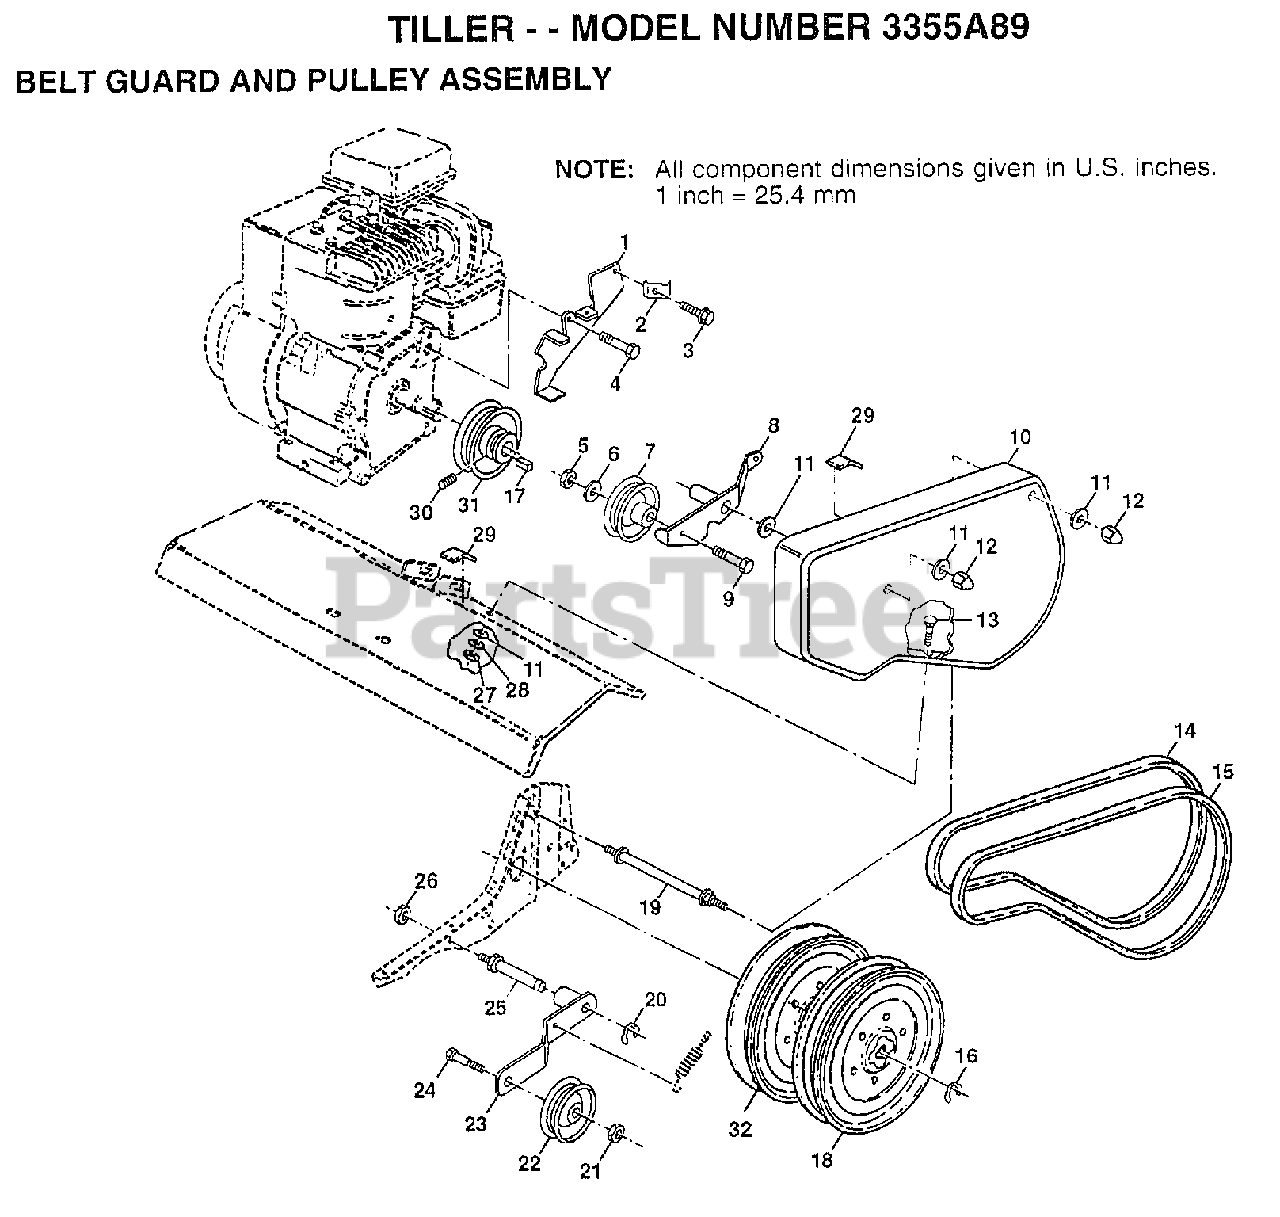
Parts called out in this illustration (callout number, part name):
1	ASM.BRKT.BELT.GRD
2	CONDIUT CLIP T
5	NUT.HEX.3/8-16UNC
6	WASHER
7	PULLEY W/SPACER
8	ARM.ASM.REV.IDLER
11	WASHER
12	NUT-CAP TI
13	BOLT T
14	BELT-V
17	KEY T
18	"SHEAVE,TRANS.""D"""
19	BOLT TI
20	KLIP RING TI
21	NUT
22	"PULLEY,IDLER"
23	"ARM, IDLER"
25	SHAFT IDLER TI
26	JAM NUT TI
28	LOCKWASHER
29	PAD IDLER TI
30	SET SCREW
31	ENGINE PULLEY TI
32	SHEAVE.TRANS
